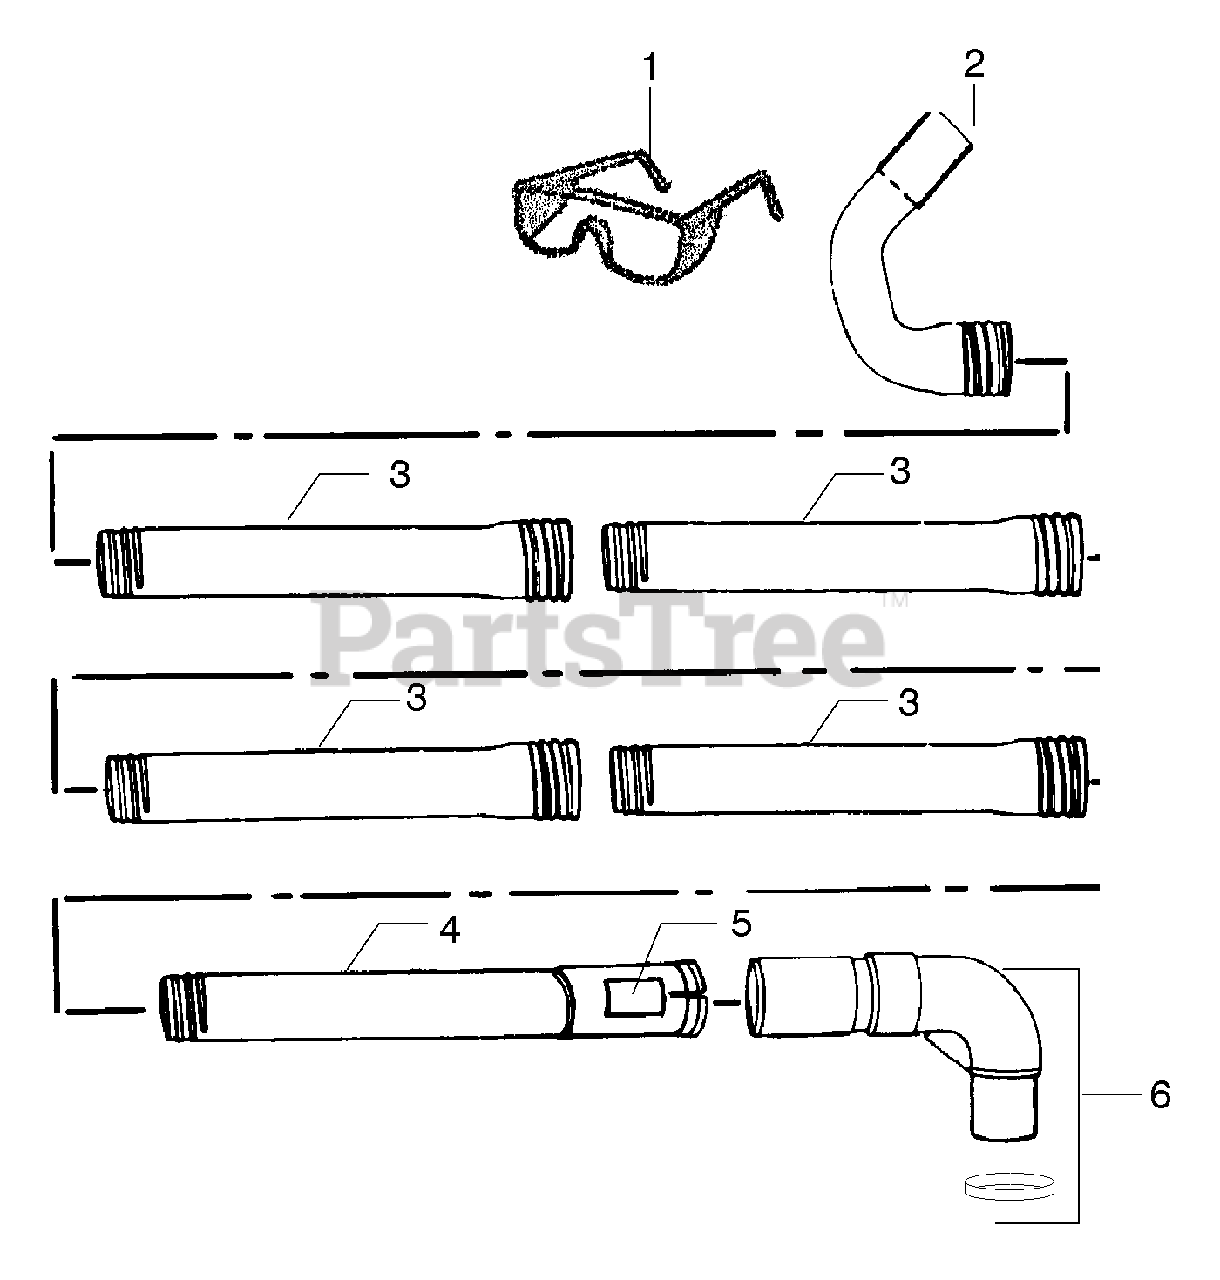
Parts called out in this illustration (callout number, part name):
3	Tube-Extension
4	Pivot Tube
5	Decal-Warning
6	Elbow & Spacer Ring
